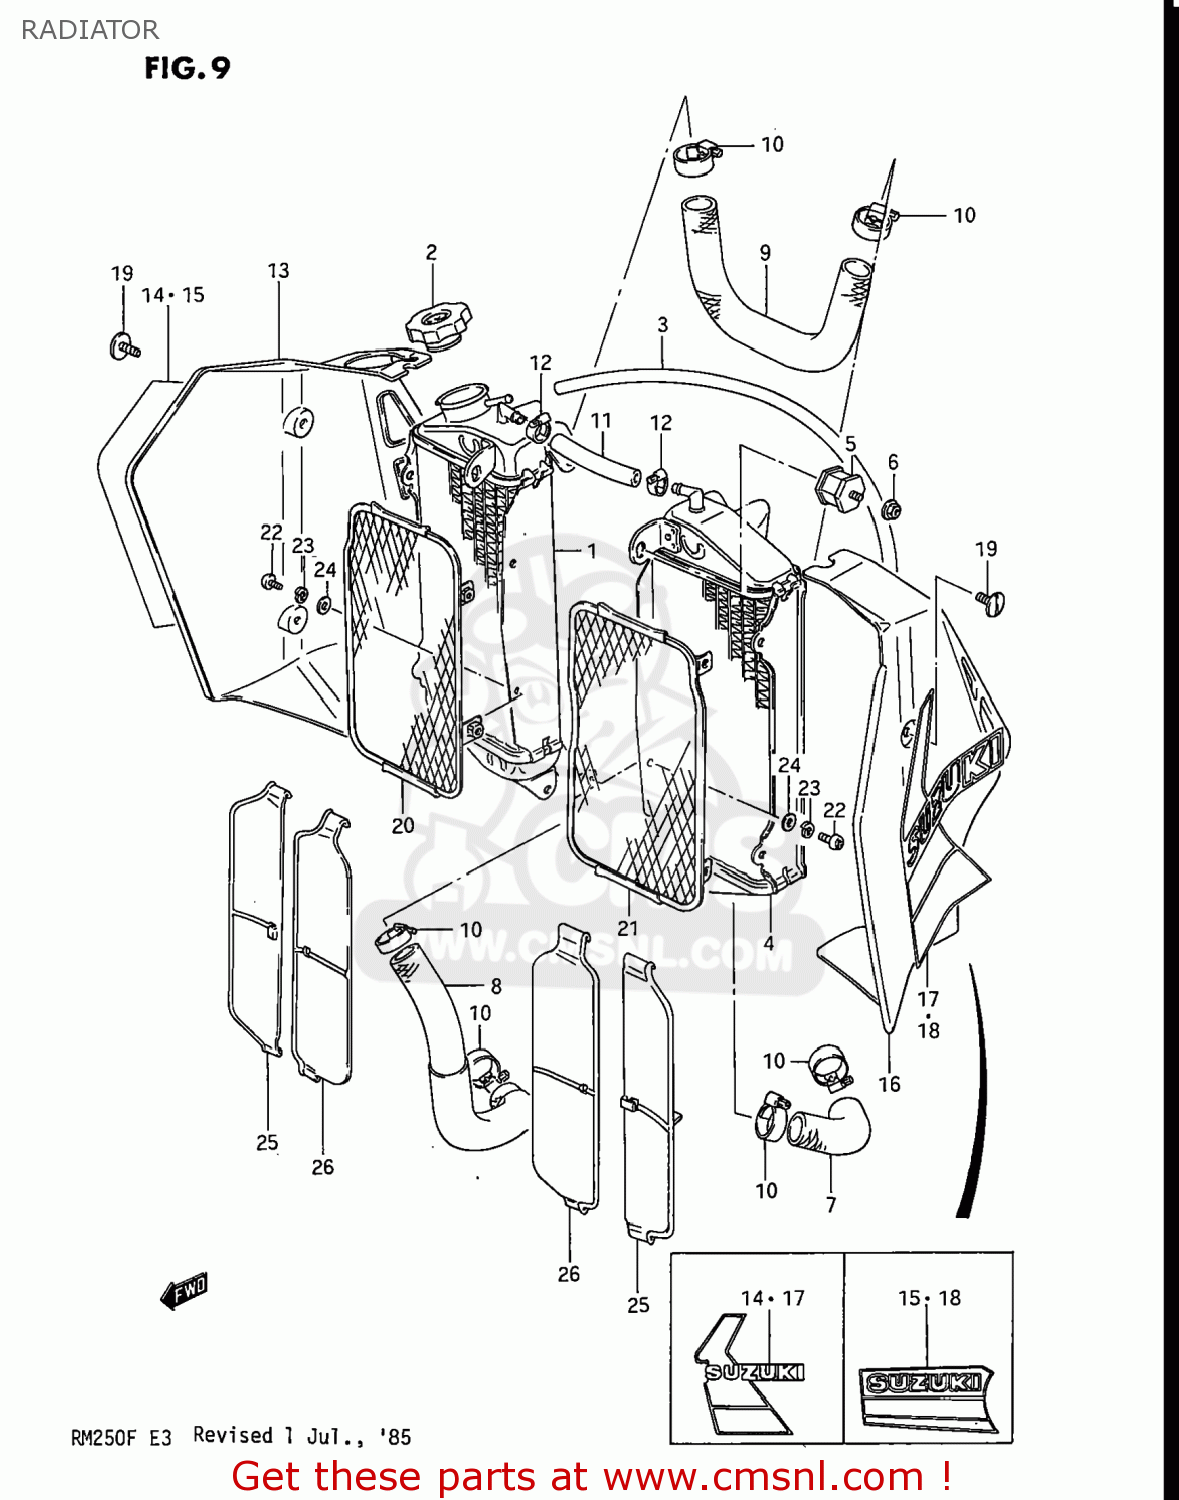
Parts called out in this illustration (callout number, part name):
1	RADIATOR ASSEMBLY,WATER
2	CAP,RADIATOR
3	HOSE
4	RADIATOR ASSEMBLY,WATER
5	CUSHION,RADIATOR
6	NUT 6MM
7	HOSE,RADIATOR
8	HOSE,RADIATOR OUTLET
9	HOSE,RADIATOR JOINT
10	CLAMP
11	HOSE,WATER
12	CLAMP
13	COVER,RADIATOR,RIGHT
14	TAPE SET
15	TAPE SET,RADIATOR COVER
16	COVER,RADIATOR,LEFT
17	TAPE SET
18	TAPE SET,RADIATOR COVER
19	SCREW(6X14)
20	BUMPER,RADIATOR,RIGHT
21	BUMPER,RADIATOR,LEFT
22	SCREW
23	LOCK WASHER
24	WASHER
25	LOUVER,RADIATOR MUD GUARD
26	LOUVER,RADIATOR MUD GUARD
